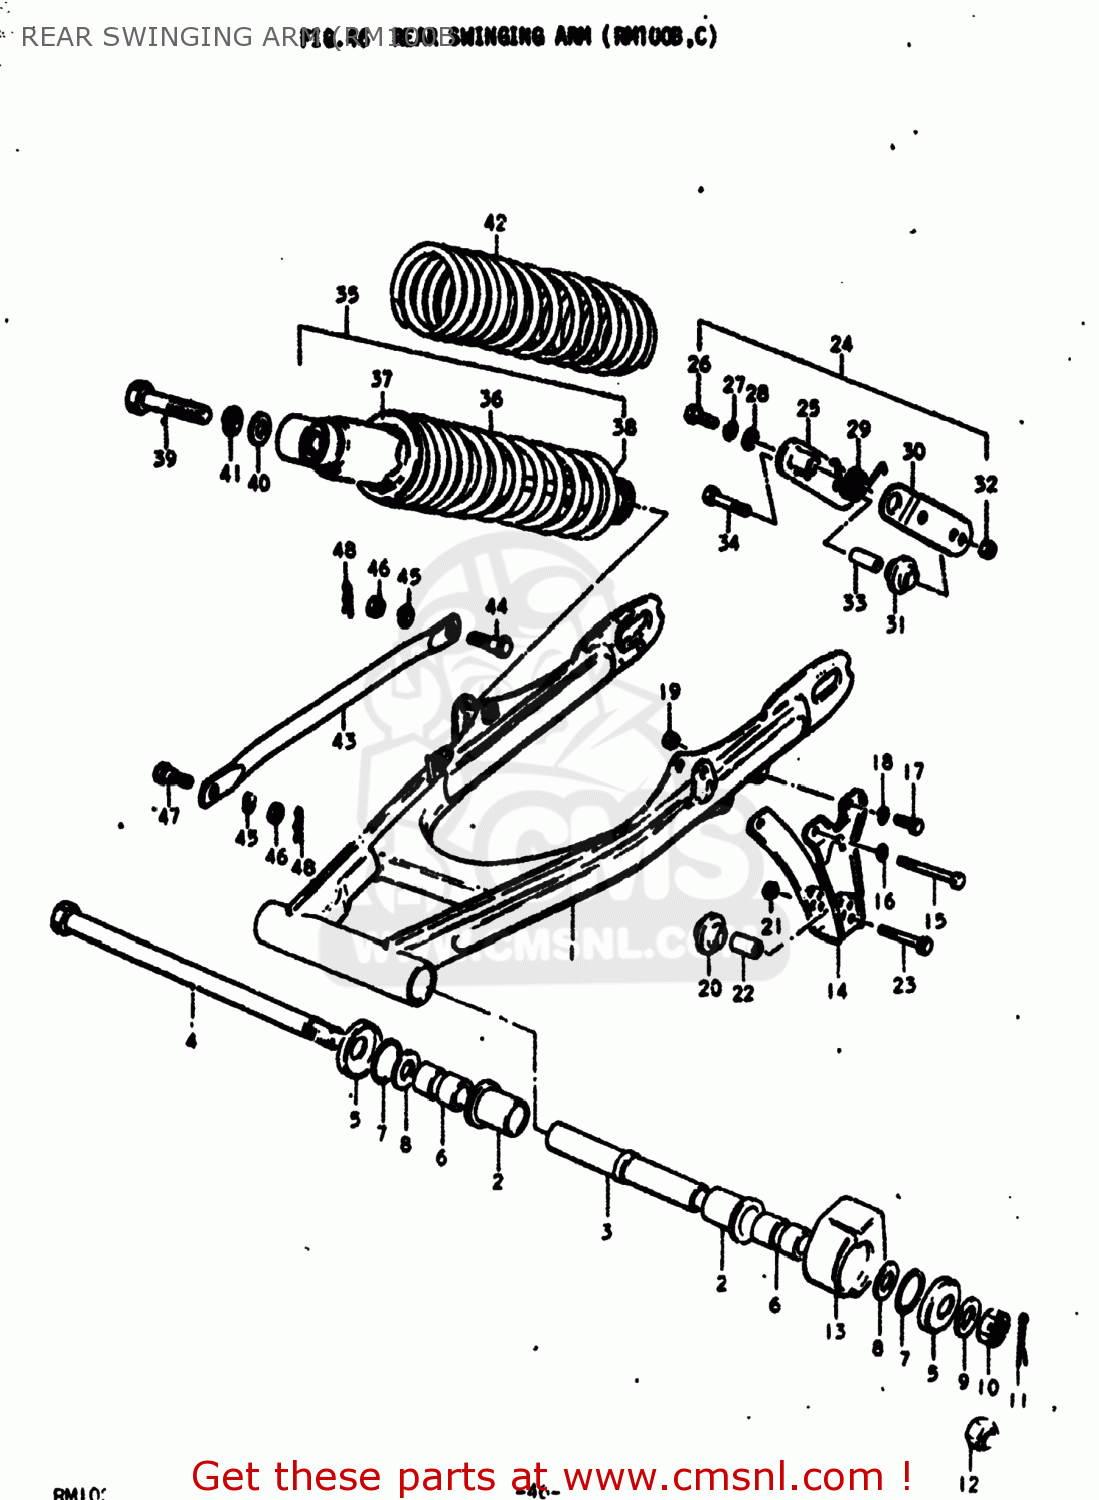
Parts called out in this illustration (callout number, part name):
1	SWING ARM ASSEMBLY,REAR
2	BUSH
3	SPACER,SWING ARM,CENTER
4	SHAFT,REAR SWING ARM
5	COVER,SWGARM BUSH DUST SEAL
6	SPACER,RR SWGARM PIVOT
7	O RING(D:2,ID:24.5)
8	WASHER(12.5X24X2.3)
9	WASHER
10	NUT, REAR AXLE
11	PIN 30X20
12	NUT 12MM
13	BUFFER,CHAIN TOUCH DEFLECTOR
14	GUIDE,CHAIN
15	BOLT
16	LOCK WASHER
17	BOLT
18	LOCK WASHER
19	NUT
20	RUBBER,CHAIN GUARD
21	NUT (6MM)
22	SPACER(6.5X10.5X22.5)
23	BOLT
25	TENSIONER,CHAIN
26	BOLT
27	LOCK WASHER
28	WASHER
29	SPRING
30	PLATE,CHAIN TENSIONER
31	RUBBER,CHAIN GUARD
32	NUT 6MM
33	SPACER(6.5X10.5X22.5)
34	BOLT
35	ABSORBER ASSEMBLY,REAR SHOCK
36	SPRING
37	GUIDE,SPRING
39	BOLT 10X40
40	WASHER
41	LOCK WASHER
42	SPRING
43	TORQUE LINK,REAR
44	BOLT(8X26.5)
45	LOCK WASHER
46	NUT
47	BOLT(8X22)
48	CLIP
